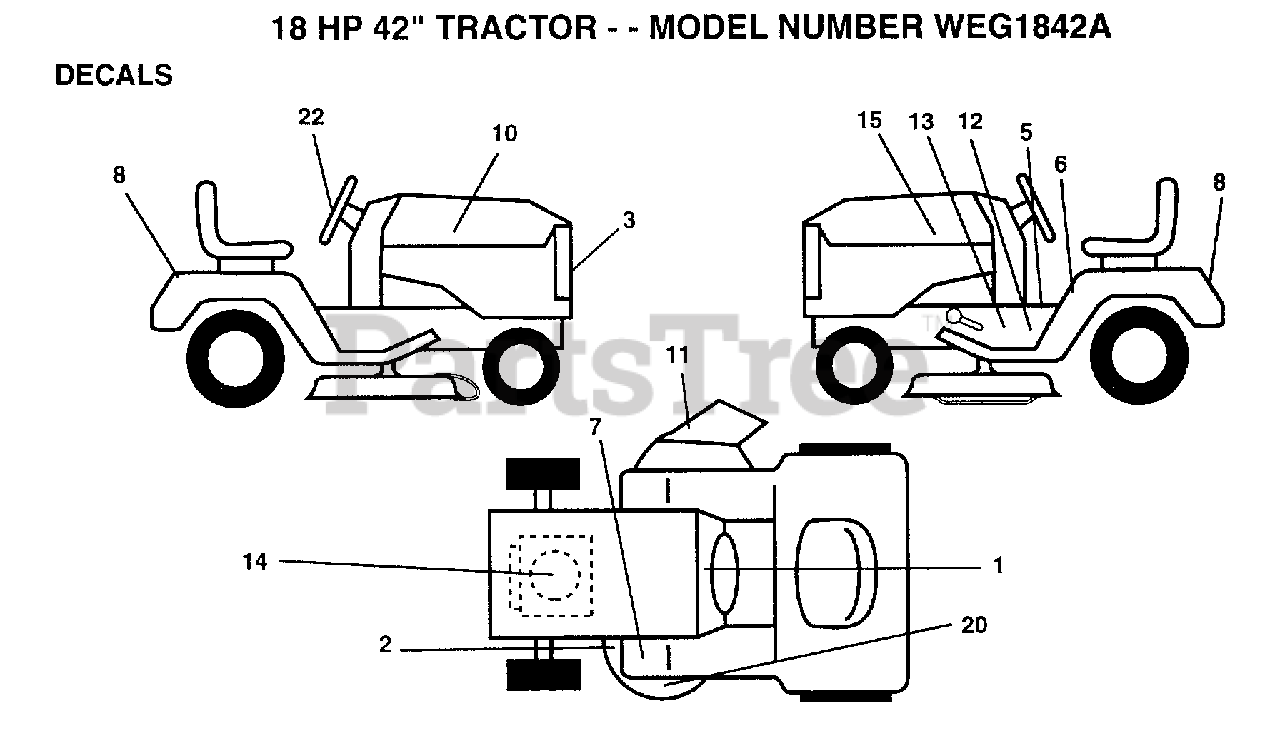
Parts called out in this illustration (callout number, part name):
1	DECAL.DASH.INSTR.
2	DECAL.V.BELT
3	DECAL.GRILL
5	DECAL BRAK PARK
6	DECAL CAUTION
7	DECAL T
8	DECAL.FENDER
10	DECAL.HOOD.RH
11	"DECAL, WARNING"
14	DECAL.ENG.272757
15	DECAL.HOOD.LH
20	DECAL.MOWER
22	DECAL.WHL.STRG.
